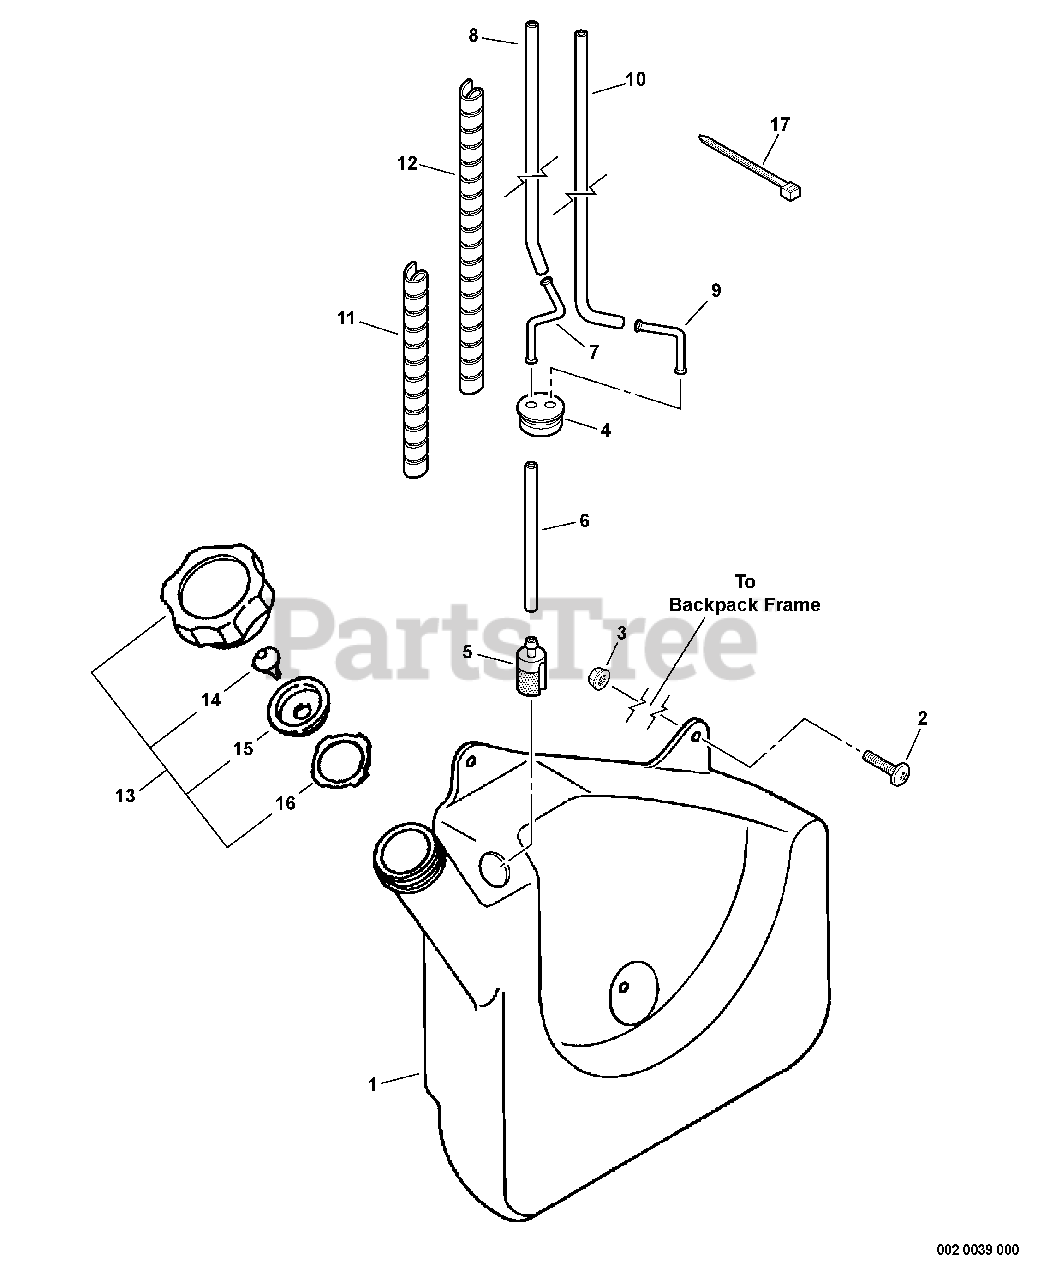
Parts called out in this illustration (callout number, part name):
1	TANK, FUEL
2	SCREW - 5X20
3	LOCKNUT - 5
4	GROMMET
5	FILTER, FUEL
6	PIPE - 3X6X280 -- BLACK
7	CONNECTOR, PIPE
8	PIPE - 3X7X520 -- BLACK
9	CONNECTOR, PIPE
10	PIPE - 2X4X480 -- CLEAR
11	WRAP, SPIRAL - 130mm
12	WRAP, SPIRAL
13	CAP ASSY
15	HOLDER, VENT
16	GASKET, CAP
17	TIE, CABLE
